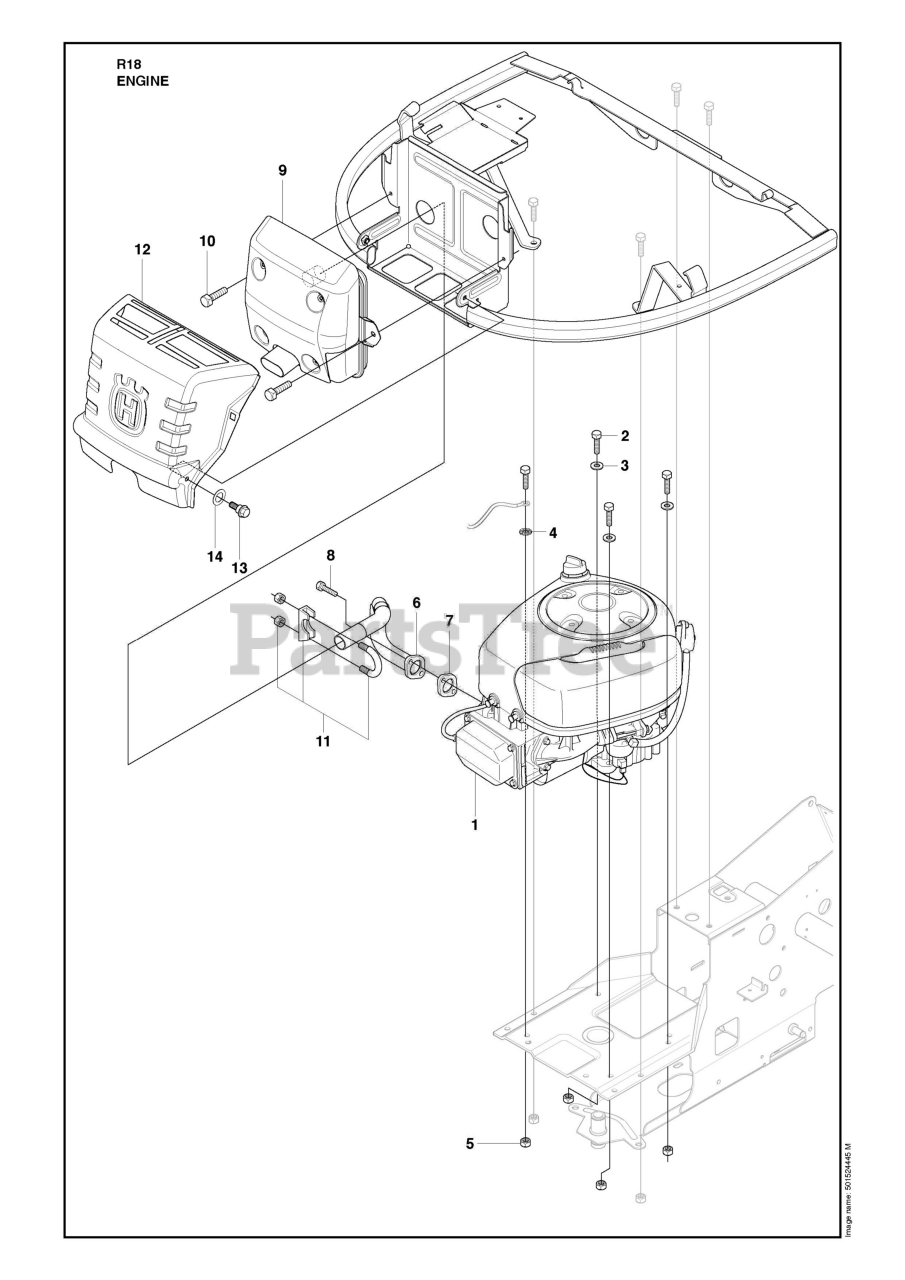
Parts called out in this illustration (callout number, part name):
3	WASHER BRB 8.4X17
5	LOCKNUT M8
6	EXHAUST PIPE ASSY
9	MUFFLER ASSY
11	CLAMP
12	HEAT PROTECTOR
14	SPRINGWASHER
